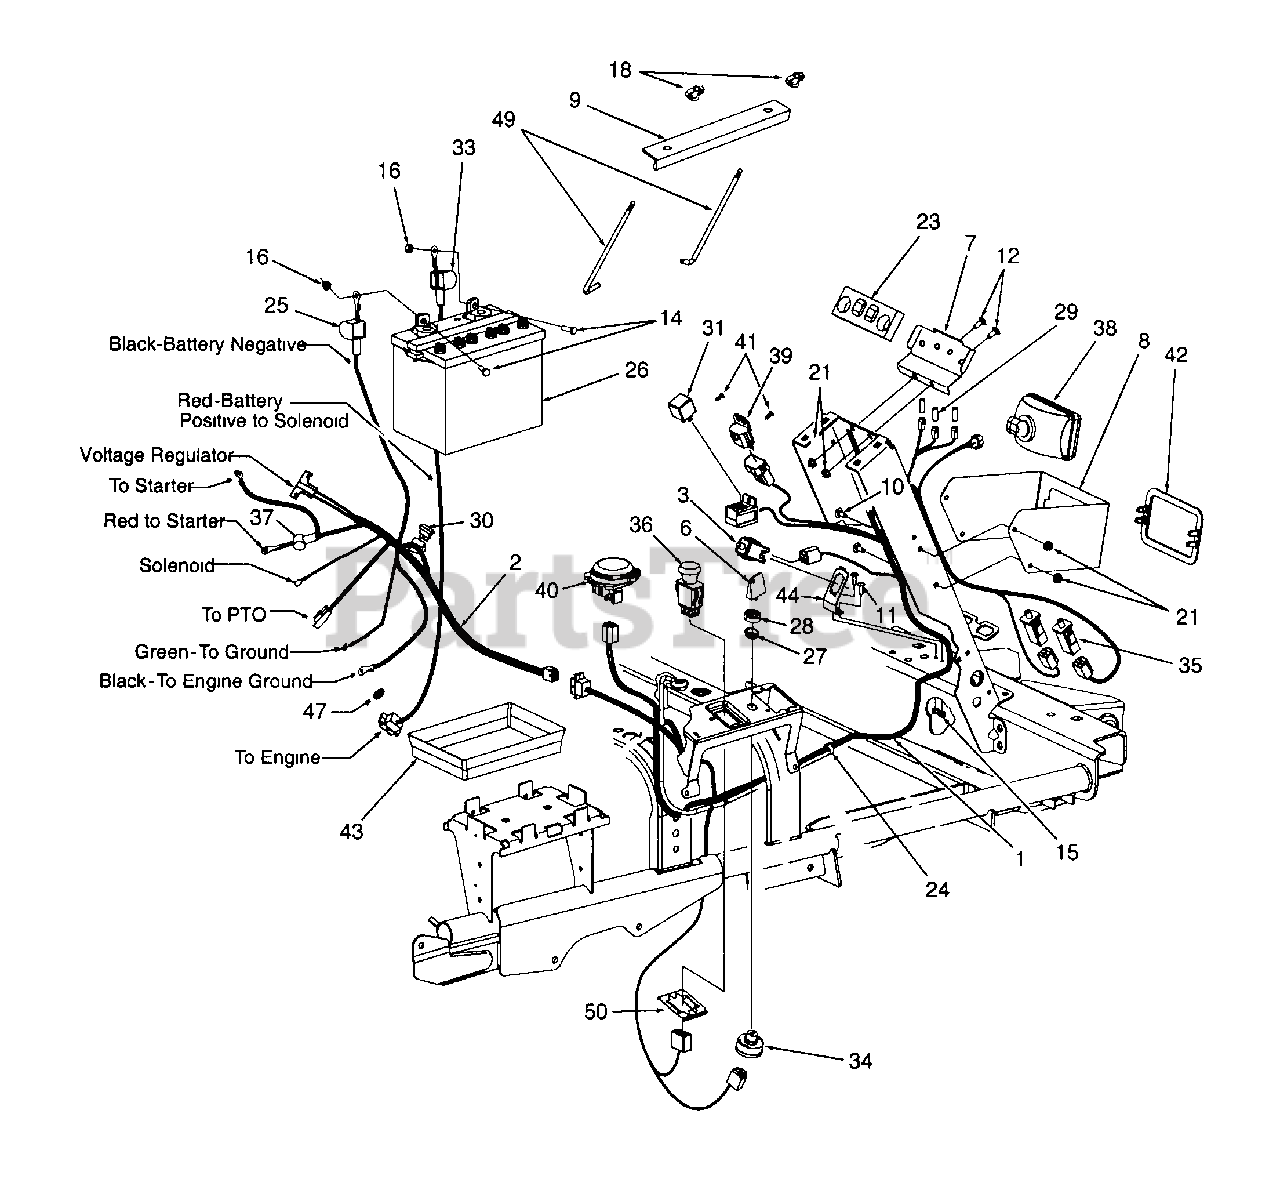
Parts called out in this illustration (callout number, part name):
1	Main Wire Harness
2	Engine Wire Harness
3	Plunger Safety Switch
6	Ignition Key
10	Carriage Bolt 1/4-20 x .62
11	Machine Screw #10-24 x 5/8
12	Hex Cap Screw 1/4-20 x .50
14	Hex Cap Screw 1/4-20 x .75
15	Hex Insert Lock Nut #10-24
16	Hex Sems Nut 1/4-20
18	Nylon Wing Nut 1/4-20
21	Hex Flange Lock Nut 1/4-20
23	Indicator Light Foam Protector
24	Cable Tie
25	Battery Terminal Cover - Black
27	Ignition Switch Nut 5/8-32
28	Ignition Switch Cap
29	Indicator Bulb
30	Mini 20 Amp Fuse
31	Relay
33	Battery Terminal Cover - Red
34	Ignition Switch
35	Plunger Safety Switch
36	PTO Switch
37	Terminal Cover - Red
38	Headlight Ass'y
39	Voltage Sensor
40	Seat Switch
41	Ratcheet Retainer
42	Headlight Bezel
43	Battery Tray
44	Switch Mounting Spring
49	Battery Retainer Rod
50	PTO Switch Retainer Bracket
